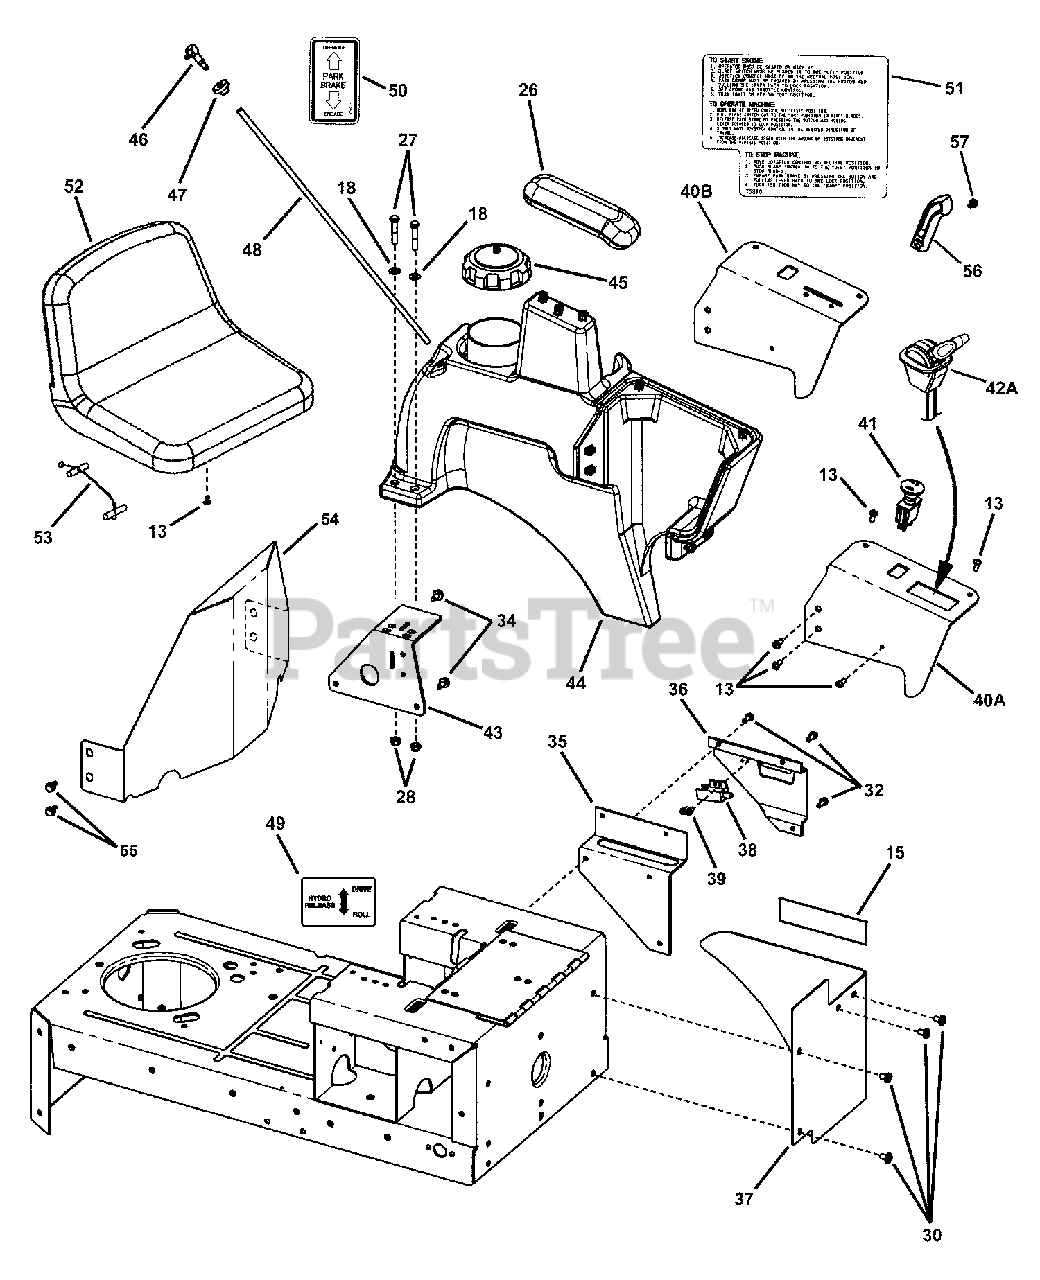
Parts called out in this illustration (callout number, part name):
13	SCREW, 1/4-20 x 5/8" Pan Head Self-Tap
15	DECAL, SNAPPER
18	WASHER, .34 x .69 x .08 Flat
26	ARM REST, HOZ
27	SCREW, 5/16-18 x 1-3/4" Hex Head Cap, GR5
28	NUT, 5/16-18 Hex Nyloc
30	SCREW, 5/16-18 x 1/2" Pan Head Self-Tap
32	SCREW, 1/4-20 x 5/8" Hex Washer Self-Tap
34	SCREW, 5/16-18 x 5/8" Hex Washer Self-Tap
35	BRACKET, L.H. Tank Support
36	BRACKET, Brake/Clutch Detent
37	FENDER, L.H. Lower
38	SWITCH, Park Brake (NC/NO)
39	SCREW, #10-24 x 1/2" Hex Washer Self-Tap (Torx)
40A	BRACKET, L.H. Console
40B	BRACKET, L.H. Console
41	SWITCH, PTO E.C. (Delta Part No. 6201-219)
42A	CONTROL, Throttle/Choke, Dual Lever
43	WELDMENT, Fuel Tank Support
44	ASSEMBLY, Fuel Tank/Left Hand Fender
45	GAS CAP w/Screw Vent
46	FITTING, Dapco
47	GROMMET
48	DIP TUBE
49	DECAL, Hydro Release
50	DECAL, Park Brake
51	DECAL, Operating Instructions
52	SEAT, Milsco High Back
53	TETHER, Seat
54	HEAT SHIELD, Engine
55	SCREW, 5/16-18 x 1/2" Hex Washer Self-Tap
56	LEVER, Throttle Control
57	RIVET, Plastic Snap
